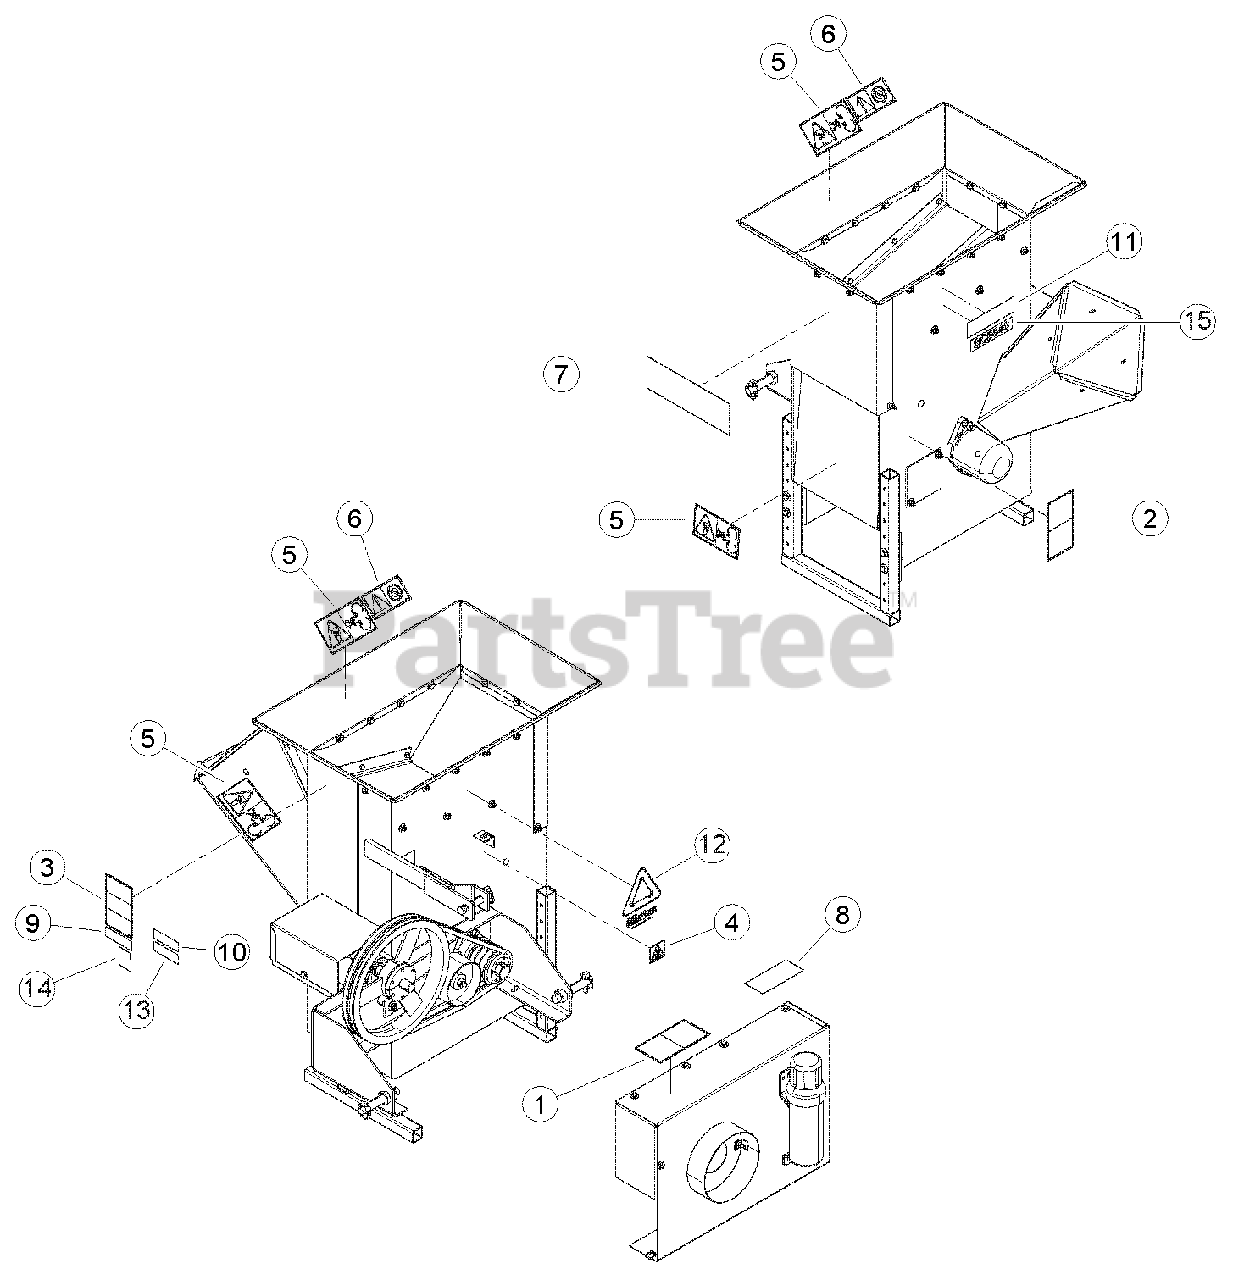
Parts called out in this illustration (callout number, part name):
1	DECAL, PTO DANGER ISO
2	DECAL, KNIFE ACCESS ISO
3	DECAL, OPERATING INSTRUCTIONS ISO
4	DECAL, SHIELD DANGER ISO
5	DECAL, BLADE DANGER ISO
6	DECAL, SHREDDER SIZE ISO
7	DECAL, ECHO BEARCAT 12.00 X 4.00
8	DECAL, MUTILINGUAL MANUAL
9	DECAL, SERIAL NUMBER
10	DECAL, PTO INFO (CE COMPLIANT ONLY)
11	DECAL, ECHO BEARCAT 6.82 X 1.90
12	DECAL, SHRED IT
13	DECAL, ATLANTIC BRIDGE LTD INFO (CE COMPLIANT ONLY)
14	DECAL, ECHO BEARCAT QR CODE
15	DECAL, MODEL SC5540
